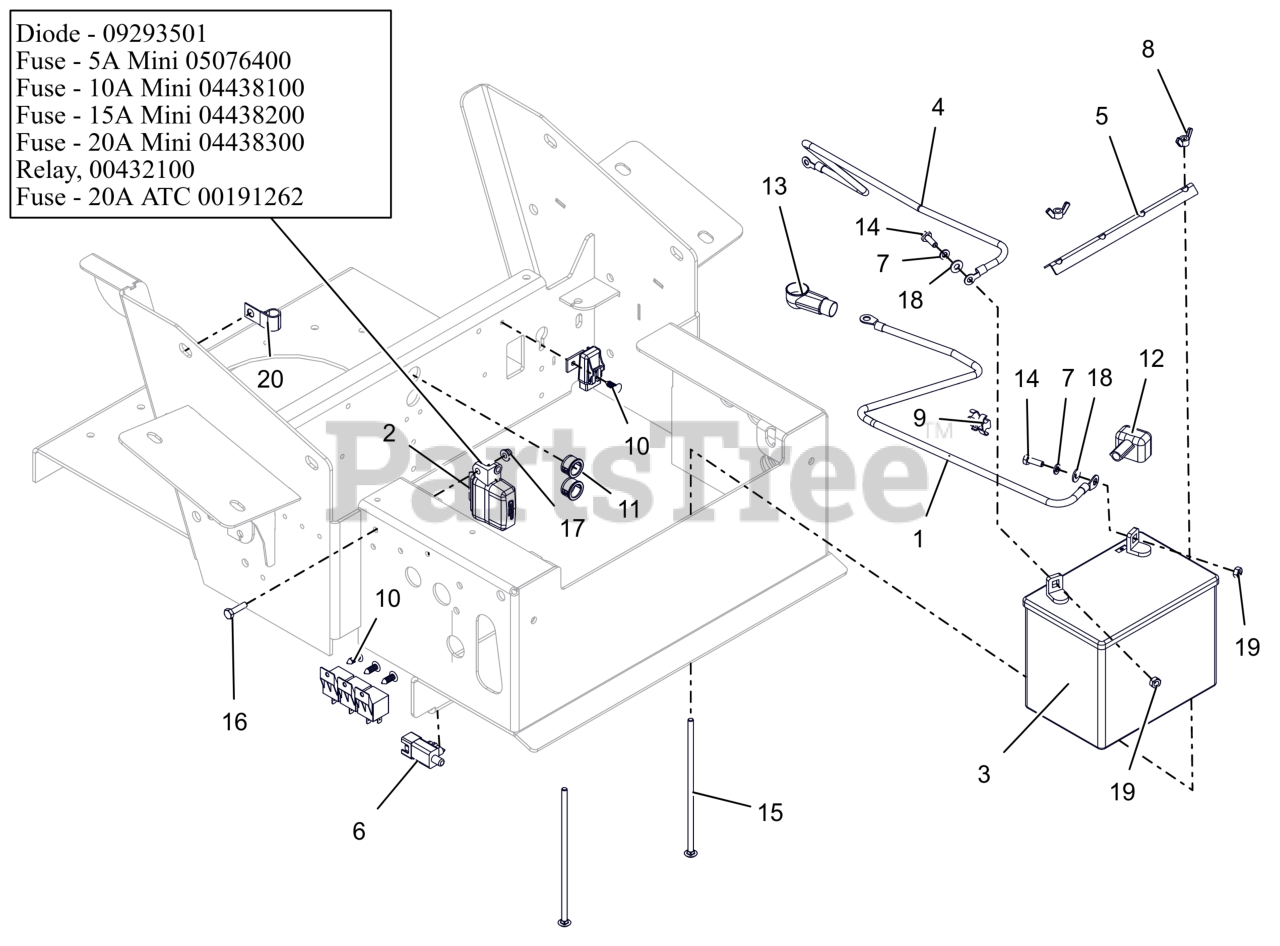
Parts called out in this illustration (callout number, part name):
1	CABLE,POS W/(2) 5/16 RING 30LG
2	HARNESS, PT100 WIRE
2	DIODE, CONNECTOR SHELL
2	FUSE, 5 AMP MINI-ATC
2	FUSE,10 AMP MINI-ATC
2	FUSE,15 AMP MINI-ATC
2	FUSE,20 AMP MINI ATC
2	RELAY,SEALED W/DIODE
2	FUSE, 20 AMP BLADE S/O
3	BATTERY, 300 CCA 10U1L
4	CABLE-NEGATIVE BATTERY 24.00"
5	HOLD DOWN
6	SWITCH, SNAP IN - N.O./N.O.
7	WSHR,LK-REG .250X.062 ZCC
8	NUT, LK-WING .25-20 ZCC
9	CLIP,T,.31-.38,
10	RIVET, .25 NYLON PANEL
11	BUSH, PANEL SNAP .687X.875X.56
12	INSULATOR
13	BOOT, .65ID POS
14	BLT, HEX .25-20X.75 G5 ZCC
15	BTL,RHSN .250-20 X 7.5 G5 ZCC
16	BLT,HEX .25-20X1.00 G5 ZCC
17	NUT,NYL-FLG .25-20 GF ZCC
18	WSHR,FLT .281X.625X.065 ZCC
19	NUT-STD .250-20 G2 ZCC
